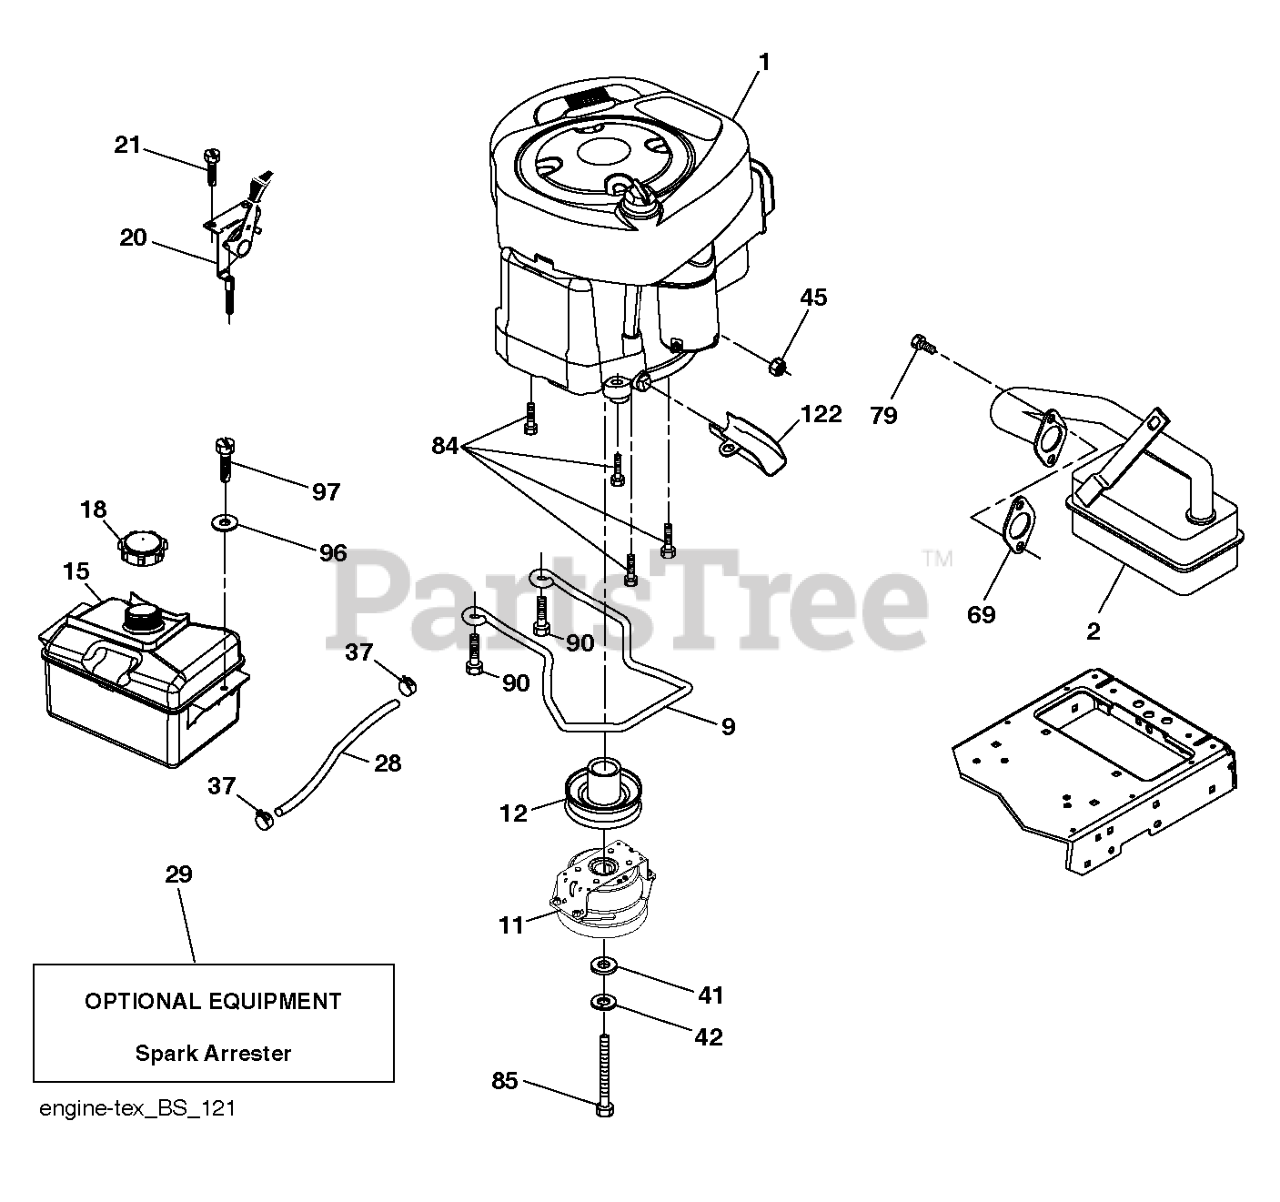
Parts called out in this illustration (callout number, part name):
2	MUFFLER.LT.BRIGGS.14HP.IC/OHV
9	KEEPER.BELT.ENGINE.3.25 (3 2)
11	RB.CLUTCH.OGURA.4.4.PD
12	PULLEY.ASM.ENG.OGURA.3
15	FUEL.TANK.ASM.NON-EPA
18	CAP ASM.FUEL.2.25"FR.
20	CONTROL.TH/CK.C.
21	SCREW.#10 X 0.750.BOS
28	LINE.FUEL.20
29	KIT.SPARK ARRESTOR 794945 B&S
37	HOSE CLAMP
42	LOCKWASHER
45	NUT
69	REPL BY 532 27 22-93
79	SCREW.SOCKET HD.5/16-1
84	SCREW.3/8-16
85	BOLT HEX 7/16-20X4-1/4"
90	SCREW 3/8-16X1
96	WASHER
97	SCREW HEXWSHR 1/4-20X3/4
122	EXTENSION DRAIN OIL
